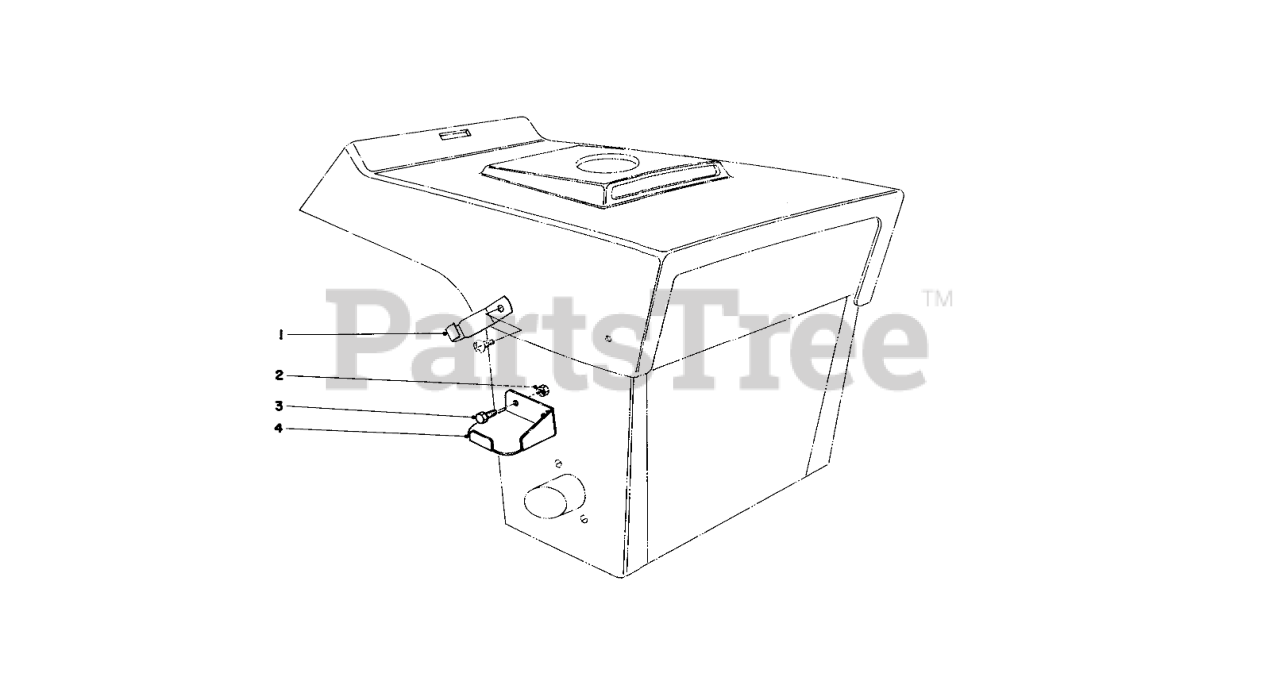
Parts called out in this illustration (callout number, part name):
1	Bracket Trimmer
2	Nut
3	SCREW-HH
4	Trimmer Support
